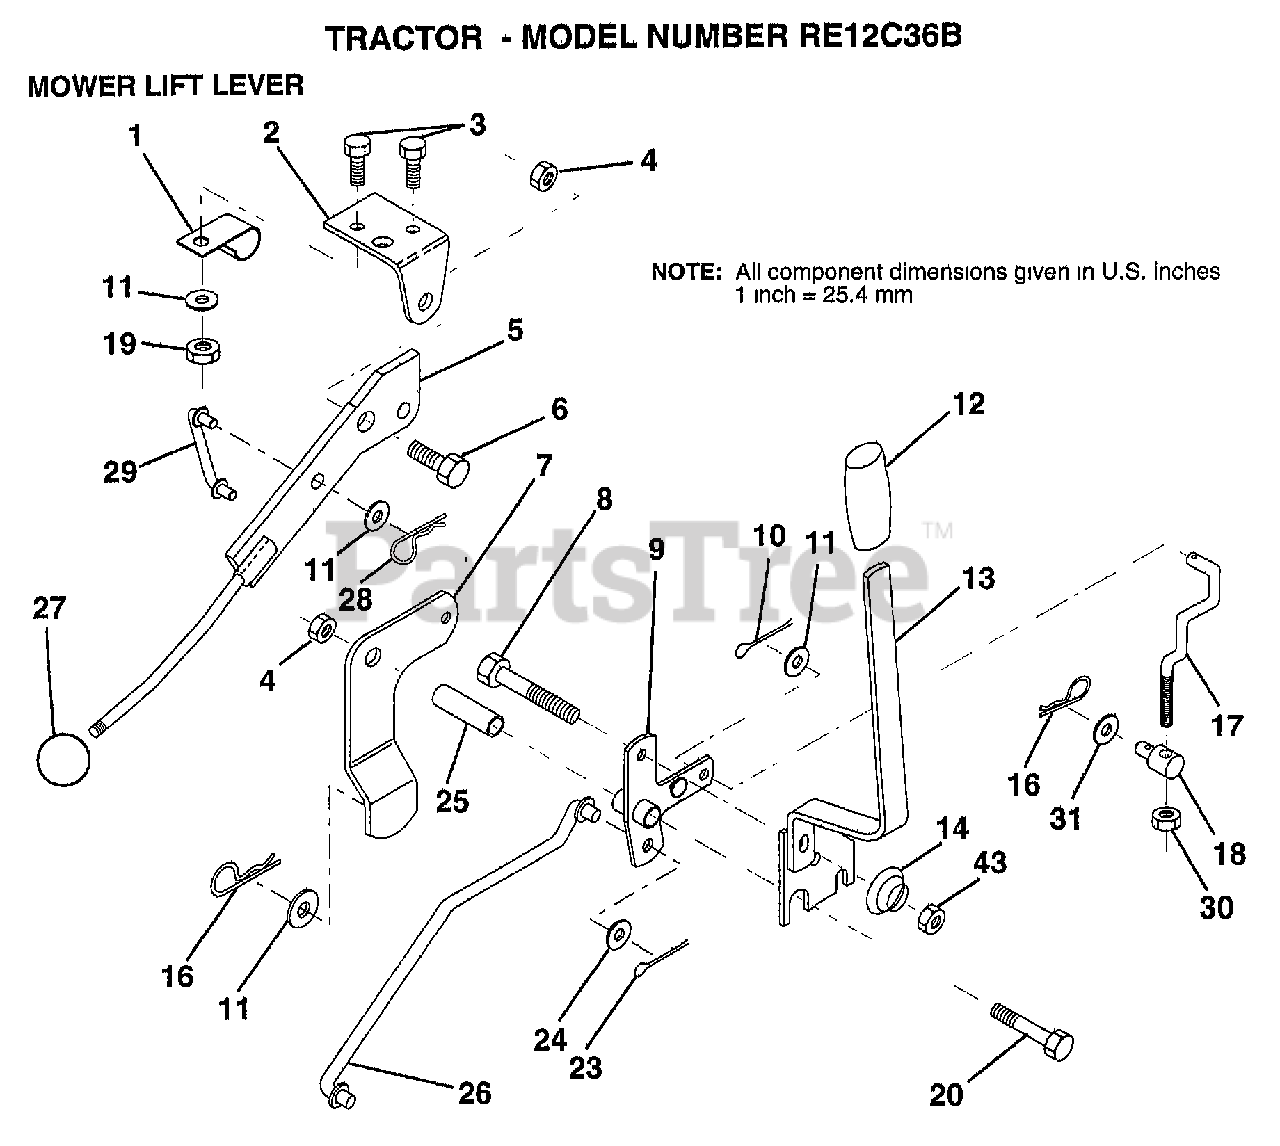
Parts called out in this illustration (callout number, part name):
1	"CLIP,INSULATOR"
2	BRKT CLUTCH
3	BOLT HXHD FIN
5	LEVER.ASM.CLUTCH
6	"BOLT, SHOULDER LT"
7	MWR CLUTCH ARM AS
8	BOLT
9	"BELLCRANK,LIFT"
10	COTTER PIN
11	WASHER
13	HANDLE.ASM.LIFT
14	SPRING COMPRESSIO
16	SPRING.RETAINER
17	"LINK,LIFT FRT"
18	TRUNION ADJ
19	NUT HXKEP 1/4X20
20	BOLT
23	PIN COTTER 1/8
25	TUBE SPACER
26	ROD LIFT MOWER
27	KNOB T(3/8 HOLE)
28	RETAINER M
29	CLUTCH LINK
30	NUT
31	WASHER
